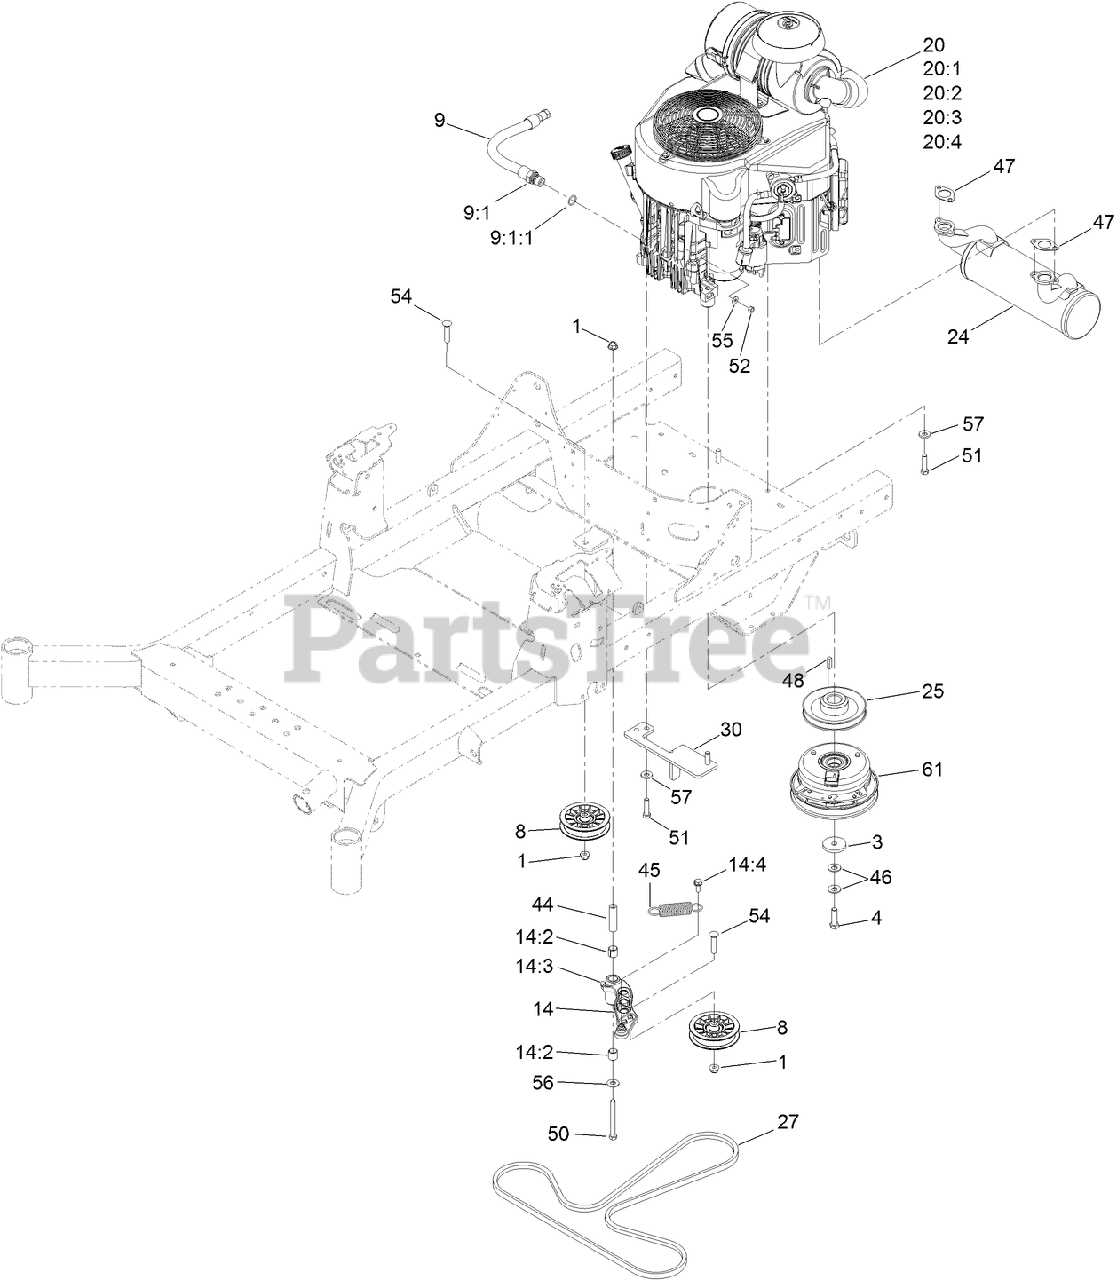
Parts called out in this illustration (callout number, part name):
1	NUT-HF, NI
3	WASHER-CLUTCH
4	SCREW-HH, W/LOCTITE
8	PULLEY-FLAT IDLER
9	ENGINE OIL DRAIN HOSE ASM
9:1	PLUG-HH
9:1:1	O-RING
14	IDLER ARM ASM
14:2	SLEEVE-BEARING
14:3	FITTING-GREASE, 90 DEG
14:4	SCREW-THD ROLL, HWH
20:1	KAWASAKI 49065-7007 ENGINE OIL FILTER
20:2	KAWASAKI 49019-7005 FUEL FILTER
20:3	KAWASAKI 11013-7045 SAFETY FILTER
20:4	KAWASAKI 11013-7044 ENGINE AIR FILTER
24	MUFFLER
25	SHEAVE (W/HUB)
27	BELT-V
30	ANCHOR-CLUTCH
44	BUSHING-PIVOT, IDLER
45	SPRING-EXTENSION
46	WASHER-SPRING
47	GASKET-EXHAUST
50	SCREW-HH
51	SCREW-HH
52	NUT-HEX
54	SCREW-CARR
55	WASHER-FLAT
56	WASHER-FLAT
57	WASHER-BELLEVILLE
61	CLUTCH
